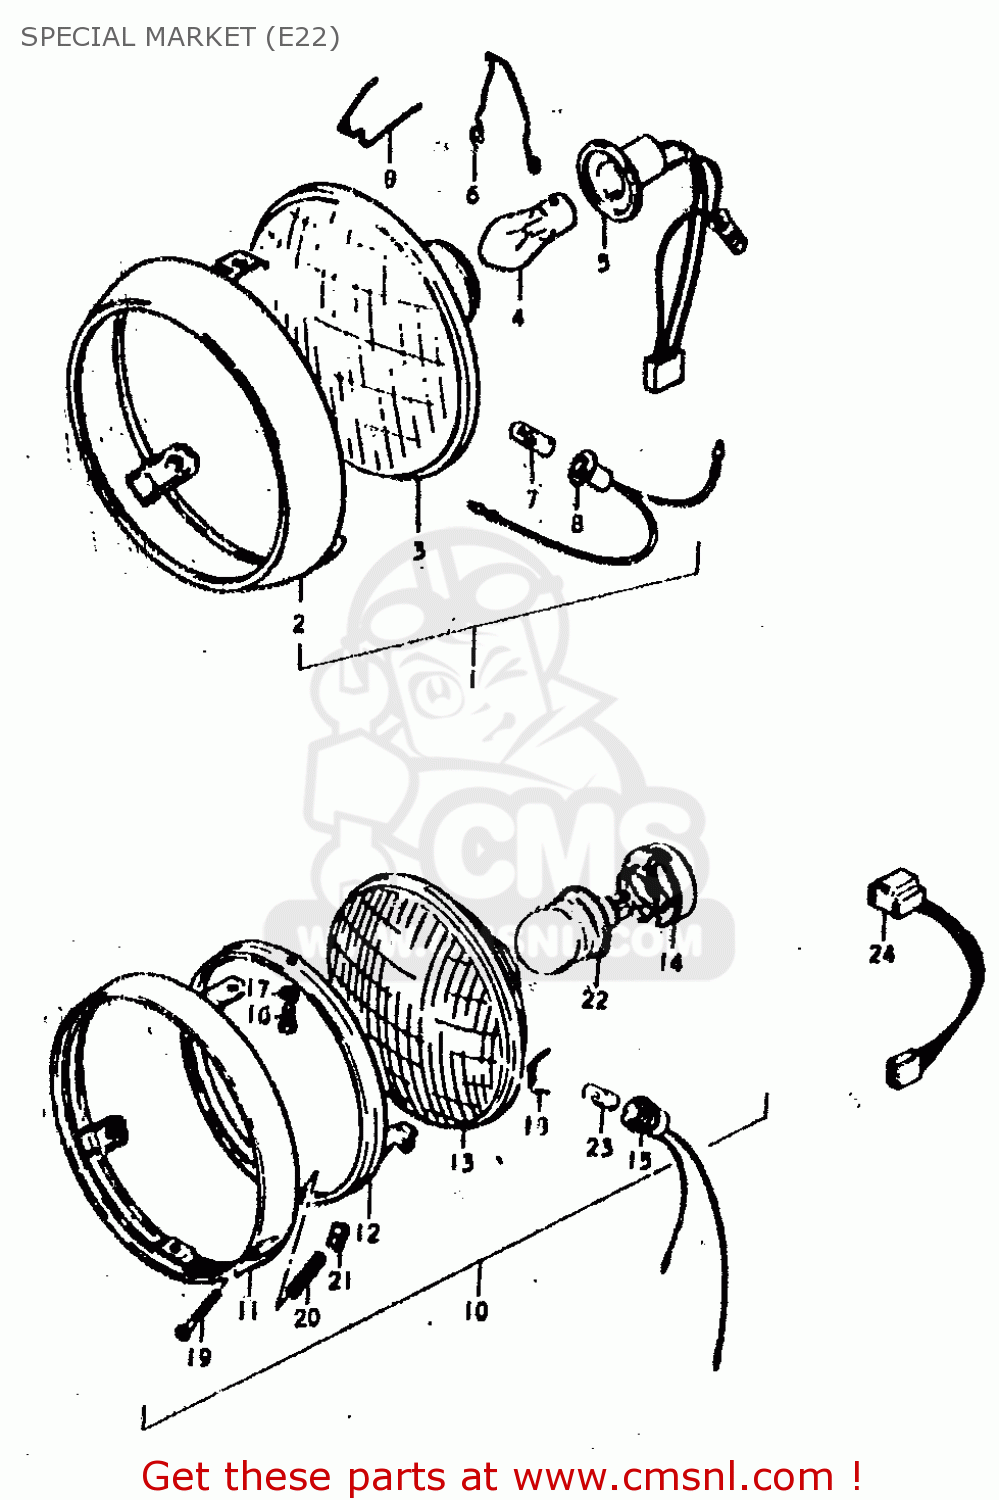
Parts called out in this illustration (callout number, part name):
1	HEADLAMP ASSY
2	RIM
3	UNIT
4	BULB(12V35/35W)
5	SOCKET
6	CLAMP,HEADLAMP
7	BULB(12V4W)
8	SOCKET
9	SPRING,HEAD LA
